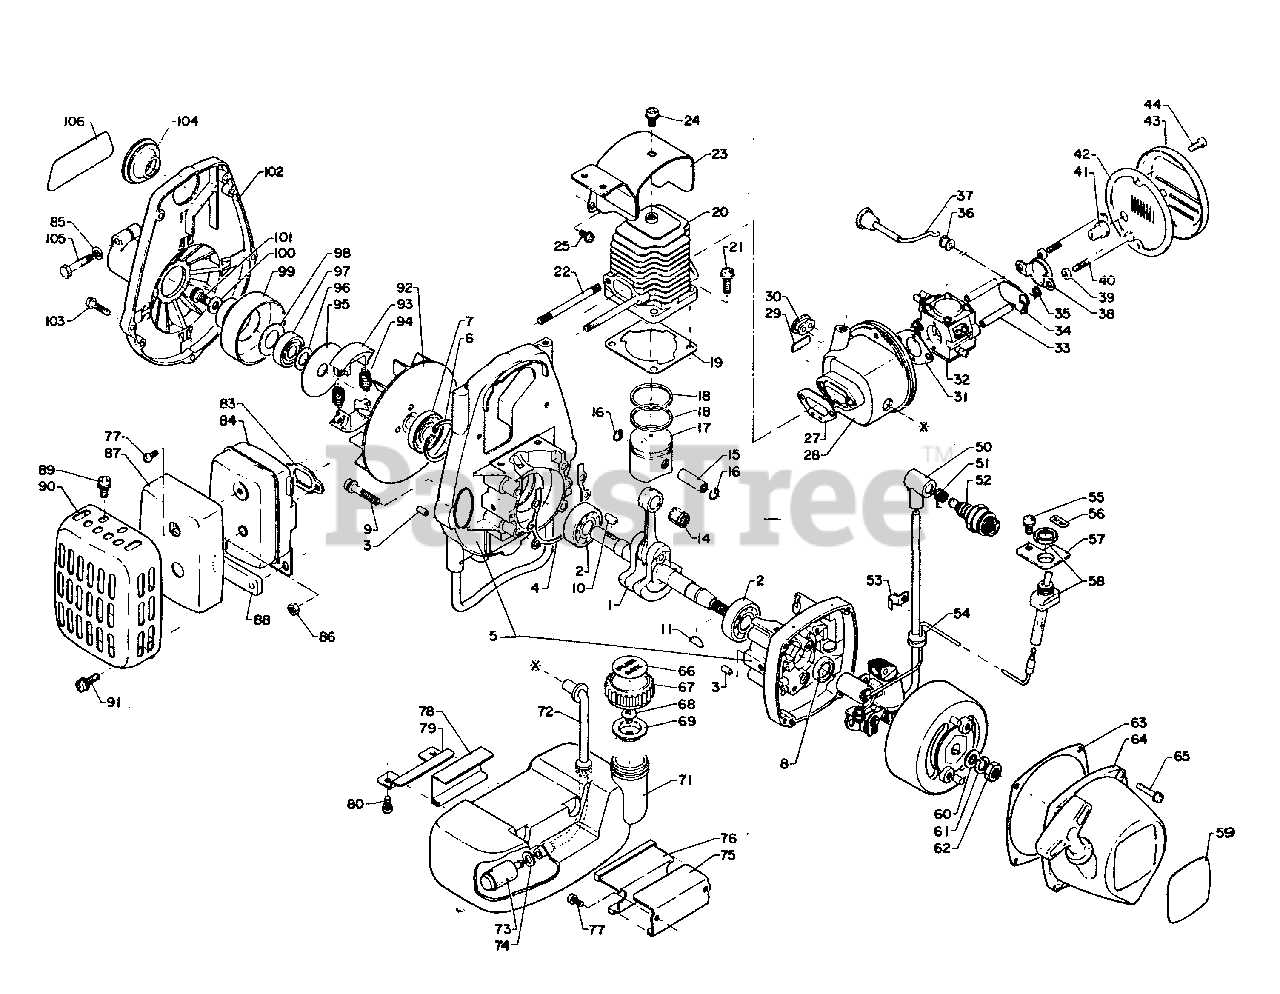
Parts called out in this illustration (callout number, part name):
1	CRANKSHAFT
2	BEARING, BALL - 6201 C3
3	PIN, LOCATING 4
4	GASKET, CRANKCASE
5	CRANKCASE KIT
6	RING, SNAP Ø32
7	SEAL, OIL 12
8	SEAL, OIL
9	SCREW 5×28
14	BEARING, NEEDLE 8
15	PIN, PISTON
16	RING, SNAP
17	PISTON
18	RING, PISTON
19	GASKET, CYLINDER
20	CYLINDER
21	SCREW 5×16
22	BOLT, STUD
23	SHIELD, CYLINDER
24	SCREW 5×10
25	SCREW - 4×8
27	GASKET, INTAKE
28	CASE, CARBURETOR
29	LABEL - CAUTION
31	GASKET, INTAKE
32	CARBURETOR - WA-21
33	SPACER
34	SHUTTER, CHOKE
35	WASHER 5.5×8×0.8
36	GROMMET, CHOKE
37	ROD, CHOKE
41	GROMMET
42	FILTER, AIR
43	COVER, AIR FILTER
44	SCREW 4×10
50	CAP, SPARK PLUG
51	TERMINAL, SPARK PLUG CAP
52	SPARK PLUG - BM6A
53	CLAMP
55	SCREW 5×10
56	LABEL, ON-OFF
57	BRACKET, SWITCH
58	IGNITION SWITCH ASSY
59	LABEL - ECHO
61	WASHER, SPRING 8
62	NUT 8×1.25
63	GASKET, STARTER
64	STARTER ASSY
65	SCREW 4×20
66	LABEL - FUEL MIX
67	CAP
68	VALVE, CHECK
69	HOLDER, CHECK VALVE
71	TANK, FUEL
72	PIPE, FUEL
73	FILTER, FUEL
74	WASHER 5.5×12×0.8
75	BRACKET, FUEL TANK
76	CUSHION, FUEL TANK
77	SCREW 4×8
78	CUSHION, FUEL TANK
79	BRACKET, FUEL TANK
80	SCREW 4×8
83	GASKET, MUFFLER
84	MUFFLER
85	WASHER, FLAT 5.5×10×0.8
86	LOCKNUT - 5
87	INSULATOR
88	SPACER
89	SCREW 5×10
90	COVER, MUFFLER
91	SCREW 5×16
92	FAN
93	SHOE, CLUTCH
94	SPRING, CLUTCH
95	PLATE, CLUTCH
96	WASHER, CLUTCH
97	BEARING, BALL 6000
99	DRUM, CLUTCH
100	WASHER 6
101	BOLT M6×10
102	CASE, FAN
103	SCREW - 4×18
104	COVER, SPARK PLUG
105	BOLT - 5×25
106	LABEL - NAME
